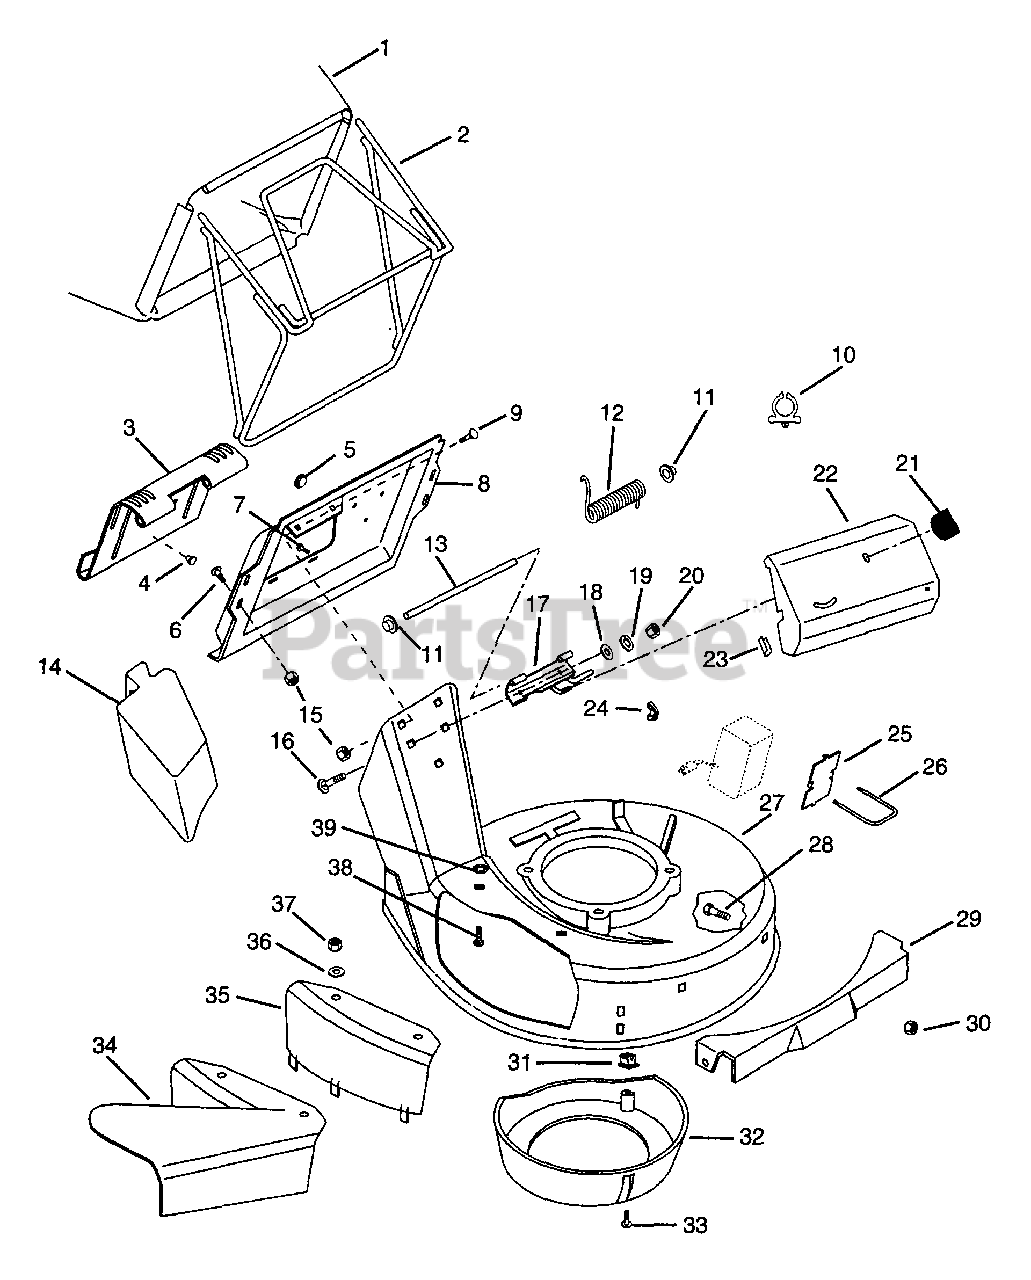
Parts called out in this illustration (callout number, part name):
1	BAG,CONSUMER BLACK 15 OZ/YD2
2	BAGGER FRAME
3	CATCHER PLATE DOOR
4	BUTTON BUMPER
6	@SCR-TAP 12-24X.50 HWH TR YWZC
6	@BLT-HEX .25-20X.50 GR5 YWZC
7	SCR-TAP 10-24X.375 TORX PHD YZ
8	CATCHER PLATE
9	@BLT-RDHDSQNK .25-20X.50 G5YZ
10	SNAP-IN CLIP
11	PUSH NUT, .25
12	SG-TORS .120X.68X3.09
13	DOOR PIN
14	MULCH MASTER MULCHER ACCESSORY
15	@NUT-SPNLK-FLG .25-20 YWZC
16	@BLT-RDHDSQNK .25-20X.75 G5YZ
17	HINGE BASE
17	HINGE BASE WELDMENT
18	@WSHR-FL-STL.312X.734X.065 YWZ
19	WSHR-LK .250X.077 HVY YWZC
20	@NUT-HEX .25-20 YWZC
21	WING - NUT
22	DRIVE COVER
23	TRIM BUMPER
24	NUT-WING #8-32 YWZC
25	BATTERY PLATE
26	U-BOLT
27	MOWER PAN W/DECALS SP/COMM
27	MOWER PAN W/DECALS SP
27	MOWER PAN W/DECALS PUSH
28	@BLT-RDHDSQNK .31-18X.50 G5YZ
29	FRONT PANEL
30	@NUT-LK-CTR .31-18 YWZC
31	PLASTIC GROMMET
32	CENTER BAFFLE
33	SCR-TAP 10-16X.62 SLPH AB YWZC
34	SIDE DISCHARGE ASSEMBLY
35	SIDE DISCHARGE COVER
36	@WSHR-FL-STL.406X.812X.065 YWZ
37	@NUT-LK-CTR .31-18 YWZC
38	BLT-RDHDSQSHK.31-18X.75 GR2 YW
39	NUT-PUSH .312
